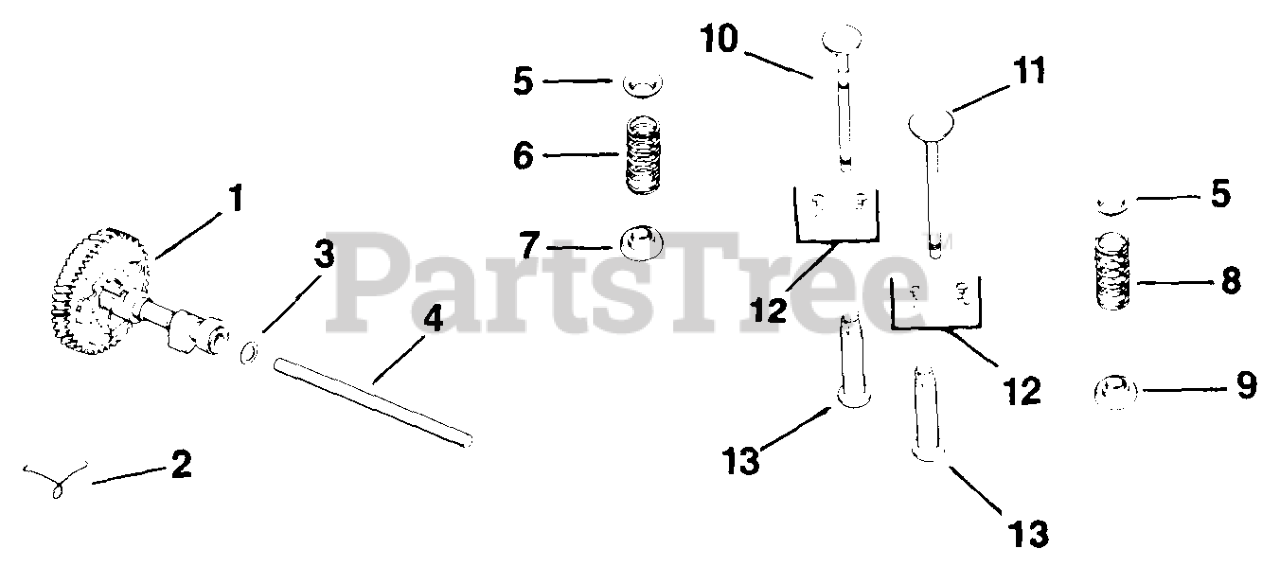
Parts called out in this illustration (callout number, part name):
1	CAMSHAFT - DISCONTINUED
2	SPRING, ACTUATING-DISCONTINUED
3	SPACER (.005")
3	SPACER (.010")
4	PIN, CAMSHAFT - DISCONTINUED
5	RETAINER, SPRING
6	SPRING, INTAKE VALVE - DISCONTINUED
8	SPRING, INTAKE VALVE - DISCONTINUED
12	KIT, RETAINER
